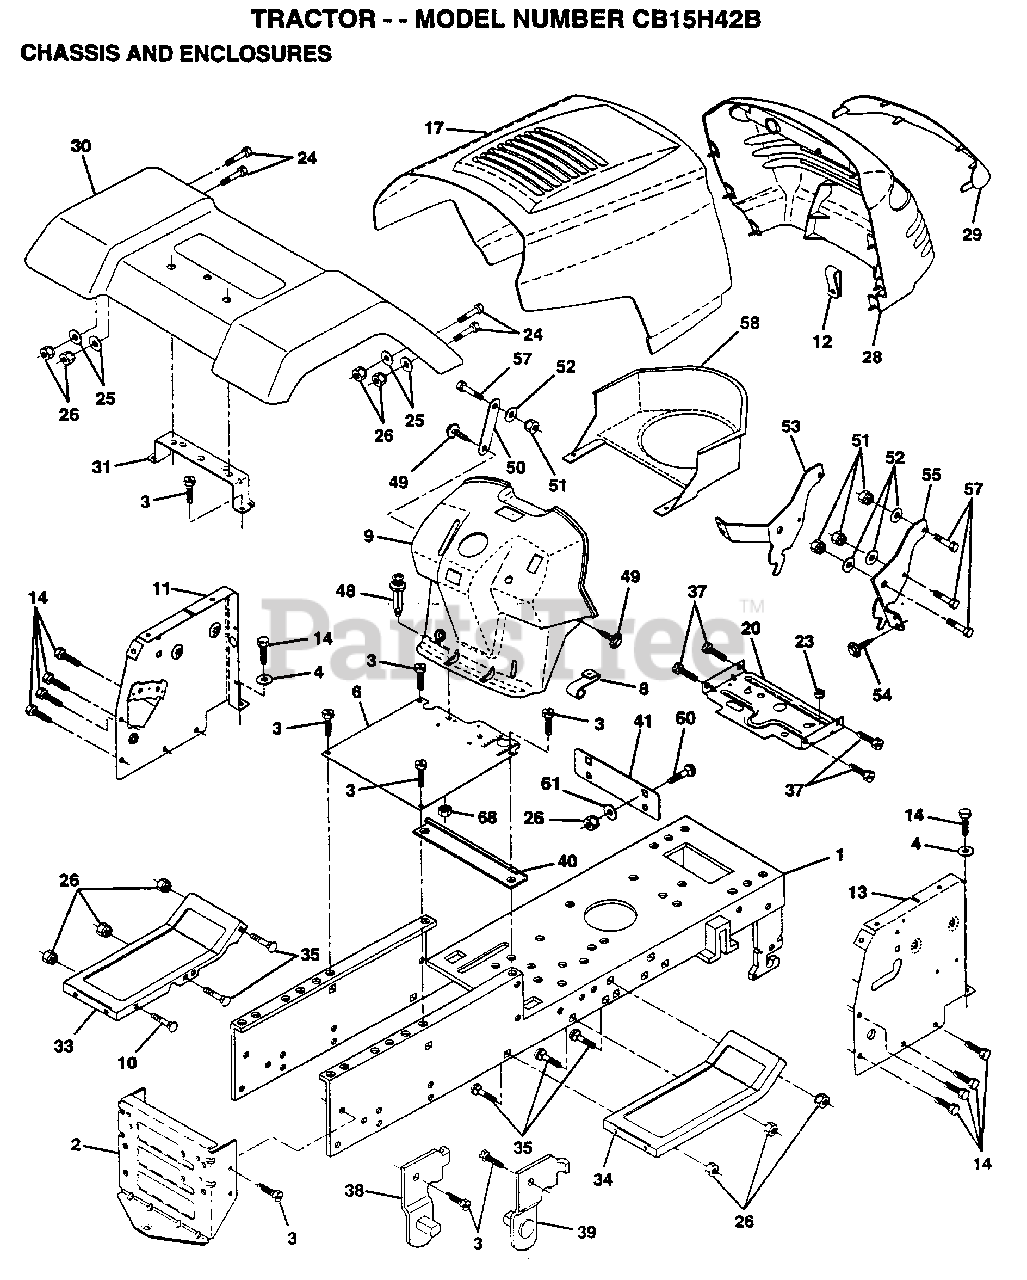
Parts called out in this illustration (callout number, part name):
1	CHASSIS.WLD.11GA
3	SCREW
4	WASHER
8	"CLIP,INSULATOR"
12	CLIP.TINNERMAN
14	SCREW LT
20	PLATE.MTG.BTRY.TK
24	BOLT
25	WASHER
26	NUT
28	GRILL.P/L.EURO.
29	LENS.P/L.EURO.
31	BRACKET SUPT FEND
33	FOOTREST.LH.LT/GT
34	FOOTREST.RH.LT/GT
35	BOLT
37	SCREW
38	BRACKET ASM LH
39	BRACKET ASM RH
40	SPACER FENDER LT
41	PLATE EXTEN FEND
48	RIVET.PUSH.PLATE
49	SCREW HEX CRT
50	BRACE SUPT DASH
51	NUT
52	WASHER
53	BRACKET.GRILLE.LH
55	BRACKET.GRILLE.RH
58	DUCT AIR 12-15H
60	BOLT
61	WASHER
68	NUT
